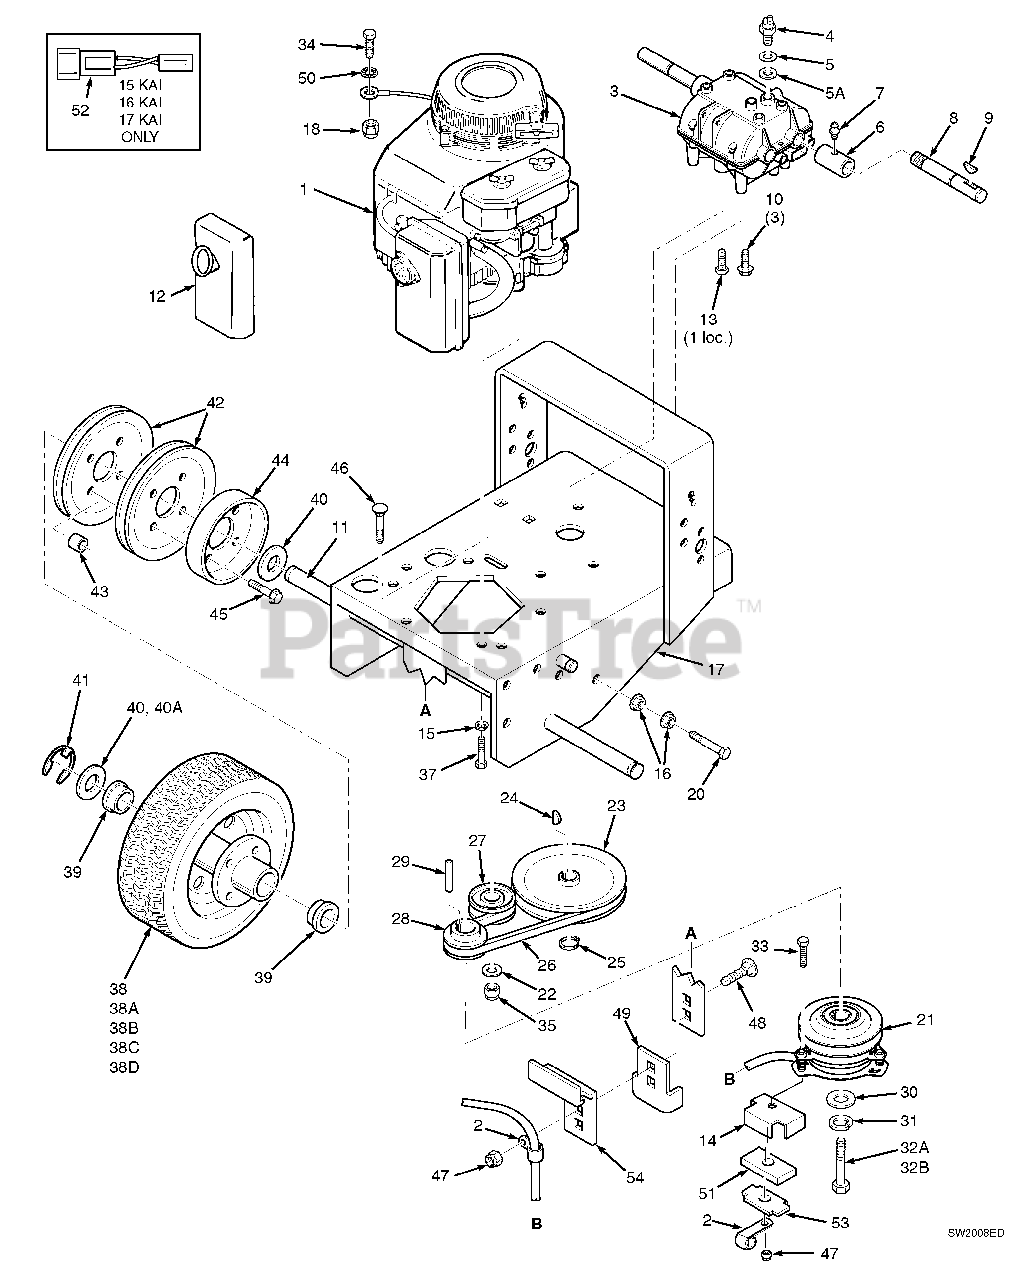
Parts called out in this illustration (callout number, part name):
1	Engine,15HP Kohler (CV 15T, Spec PS-41621)
1	Engine, 15HP Kawasaki (Spec FH430V-BS33-R)
2	Cable Clamp
3	Transmission, 5-speed (Peerless 700-070, 9 tooth spline)
4	Neutral Safety Switch
5	Fibre Washer, thin
5A	Fibre Washer, thick
6	Coupler, Jackshaft
7	Grease Fitting, straight 1/4-28
8	Jackshaft
9	Key, Hi-Pro #9
10	Bolt, 5/16-18 X 3/4" Hex Head
11	Wheel Axle
11	Wheel Axle (SW 32)
12	Muffler
13	Bolt, 5/16-18 X 3/4" Hex Head
14	Backing Plate
15	Lock Wshr. 5/16"
16	Nut, 3/8-16 Serrated Flange
17	Engine Deck (fits SW32)
17	Engine Deck
18	Nut, 1/4-20 Elastic Stop
19	Nut, 5/16-18 Serrated Flange
20	Bolt, 3/8-16 x 3-3/4" Hex Head
21	Electric Clutch (Ogura)
22	Washer, 3/8" (.391 x .938 x .105)
23	Pulley, Transmission Input
24	Key, Woodruff #9
25	Retaining Ring, 5/8" Ext, Basic
26	Belt, Transmission Drive
27	Idler Pulley, Transmission
28	Pulley, Traction Drive
29	Key, 1/4 x 1/4 x 3/4"
30	Flat Washer, 7/16" Special
31	Lock Washer, 7/16"
32A	Bolt, 7/16-20 x 2-1/2" Hex Head
32B	Cpsrw, M10-1.5 x55 Metric Hex Hd
33	Bolt, 5/16-18 x 1-3/4" Hex Head
34	Bolt, M8-1.25 x 1.0
35	Nut, 3/8-16 Elastic Stop
36	Flat Washer, 5/16"
37	Bolt, M8-1.25 x M25 Metric Hex Hd
38	Wheel Assembly
38	Wheel Assembly (SW32)
38A	Tire, 13 x 6.50-6, 2-ply
38B	Rim & Bearing Assembly
38C	Tire, 13 x 5.00-6 2-ply
38D	Rim Assembly
39	Wheel Bearing
40	Washer, 1-1/16 x 1-3/4 x 12 ga
40A	Washer, 1-1/16 x 1-1/2 x 18 ga
41	Retaining Ring, 1" Ext.- "E"
42	Pulley, Wheel Drive
43	Spacer, Wheel Pulley
44	Brake Drum
45	Bolt, 5/16-18 x 1-1/2" Serrated Flange
46	Bolt, 3/8-16 x 2" Carriage
47	Nut, 5/16-18 Elastic Stop
48	Bolt, 5/16-18 x 1" Carriage
49	Anti Rotation Bracket
50	Lock Washer Internal Tooth
51	Rubber Pad, Clutch Stop
52	Wire Harness Adapter
53	Plate, Backing
54	Plate, Clutch Bracket
